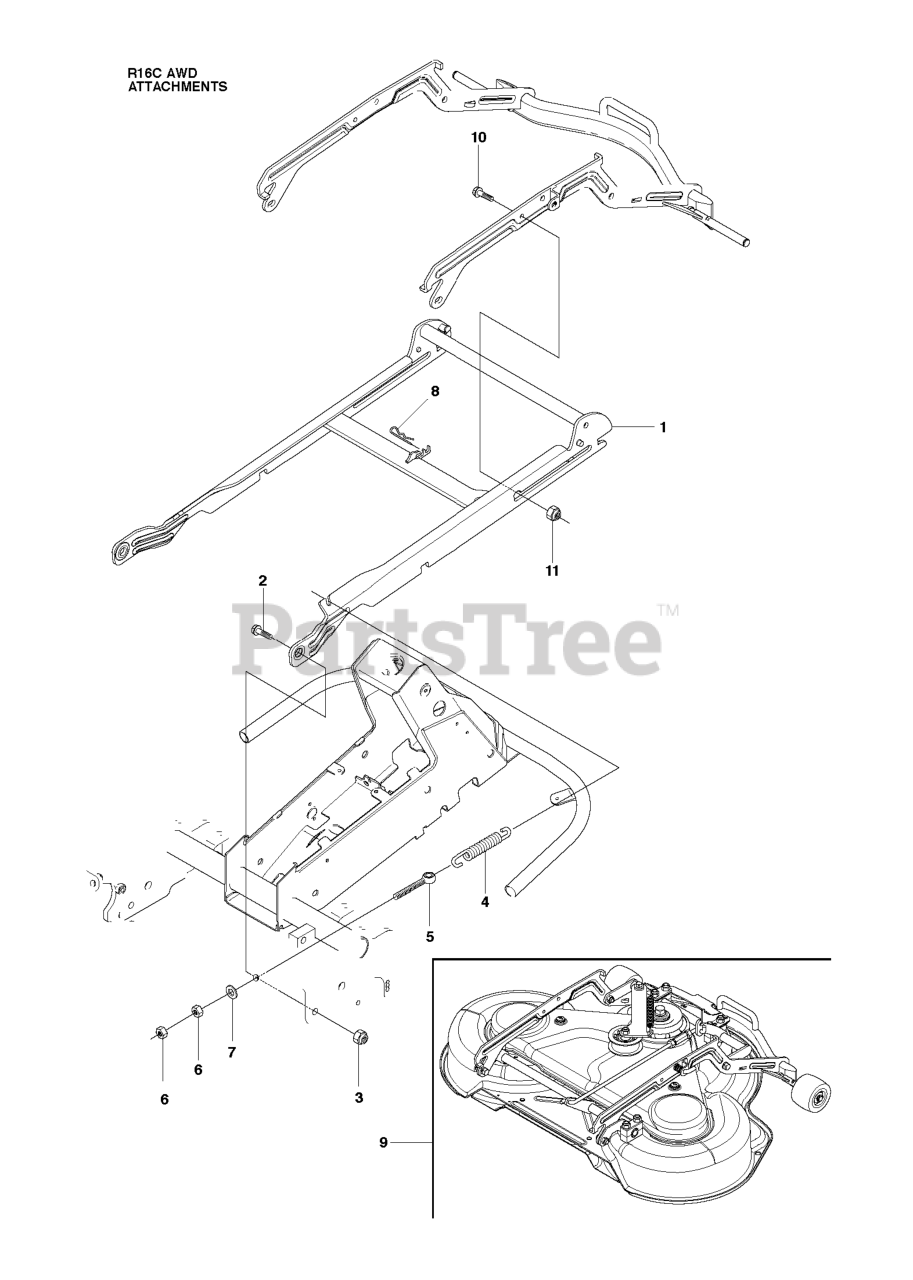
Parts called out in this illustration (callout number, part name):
6	NUT
7	WASHER
10	COLLAR SCREW
11	LOCKNUT M8
